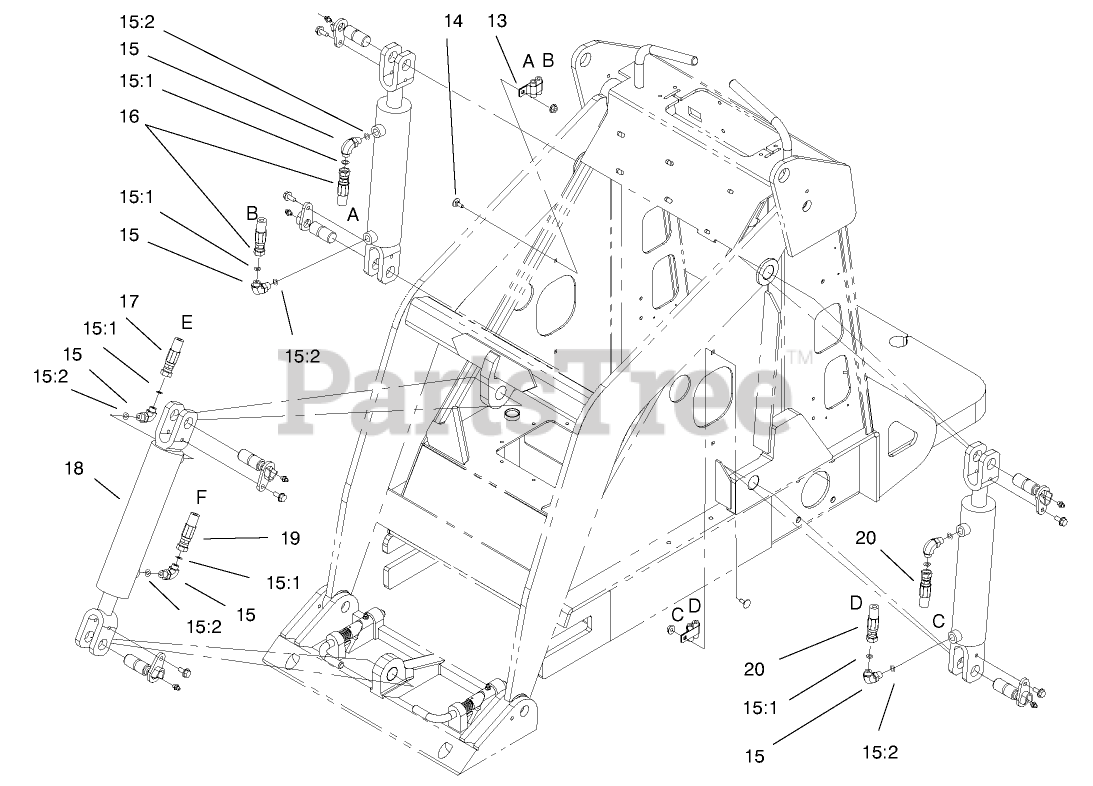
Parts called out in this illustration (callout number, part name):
13	CLAMP-R, DOUBLE
14	BOLT-CARR
15	FITTING-ELBOW 90
15:1	O-RING
15:2	O-Ring
16	HOSE-HYD
17	HOSE-HYD
18	Hydraulic Cylinder
19	HOSE-HYD
20	HYD HOSE ASM
